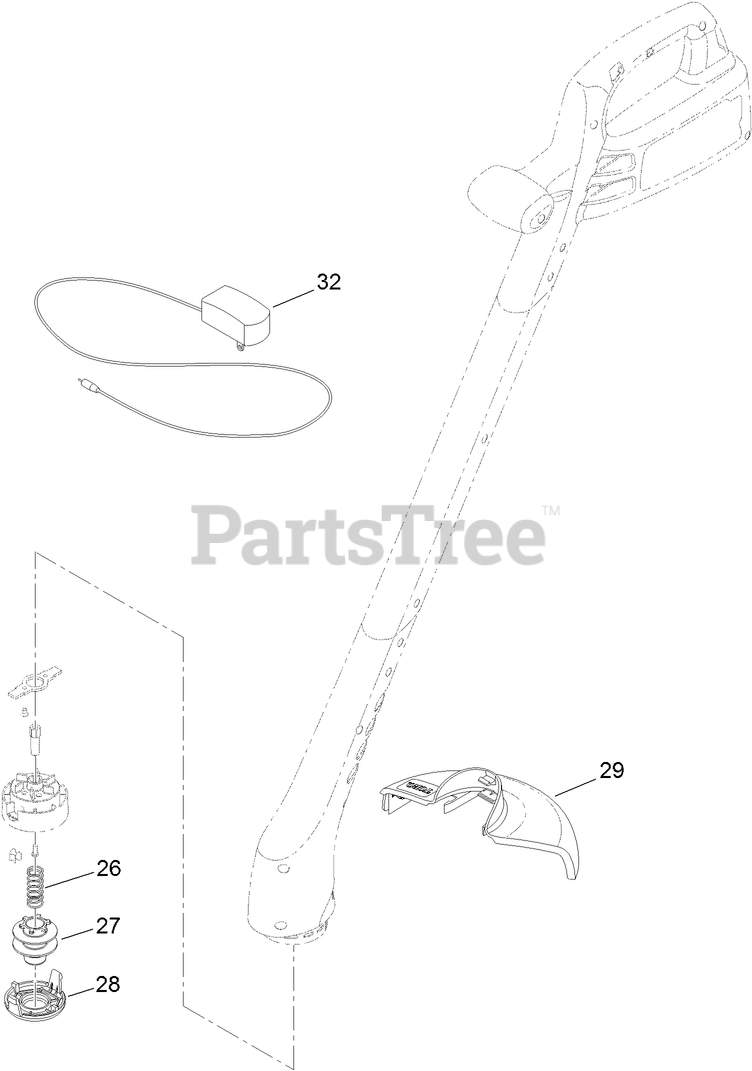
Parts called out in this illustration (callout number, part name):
26	SPRING-COMPRESSION
27	SPOOL ASM
28	CAP-SPOOL, 7 INCH
29	8 INCH SHIELD ASM
32	CHARGER-BATTERY, 12V
